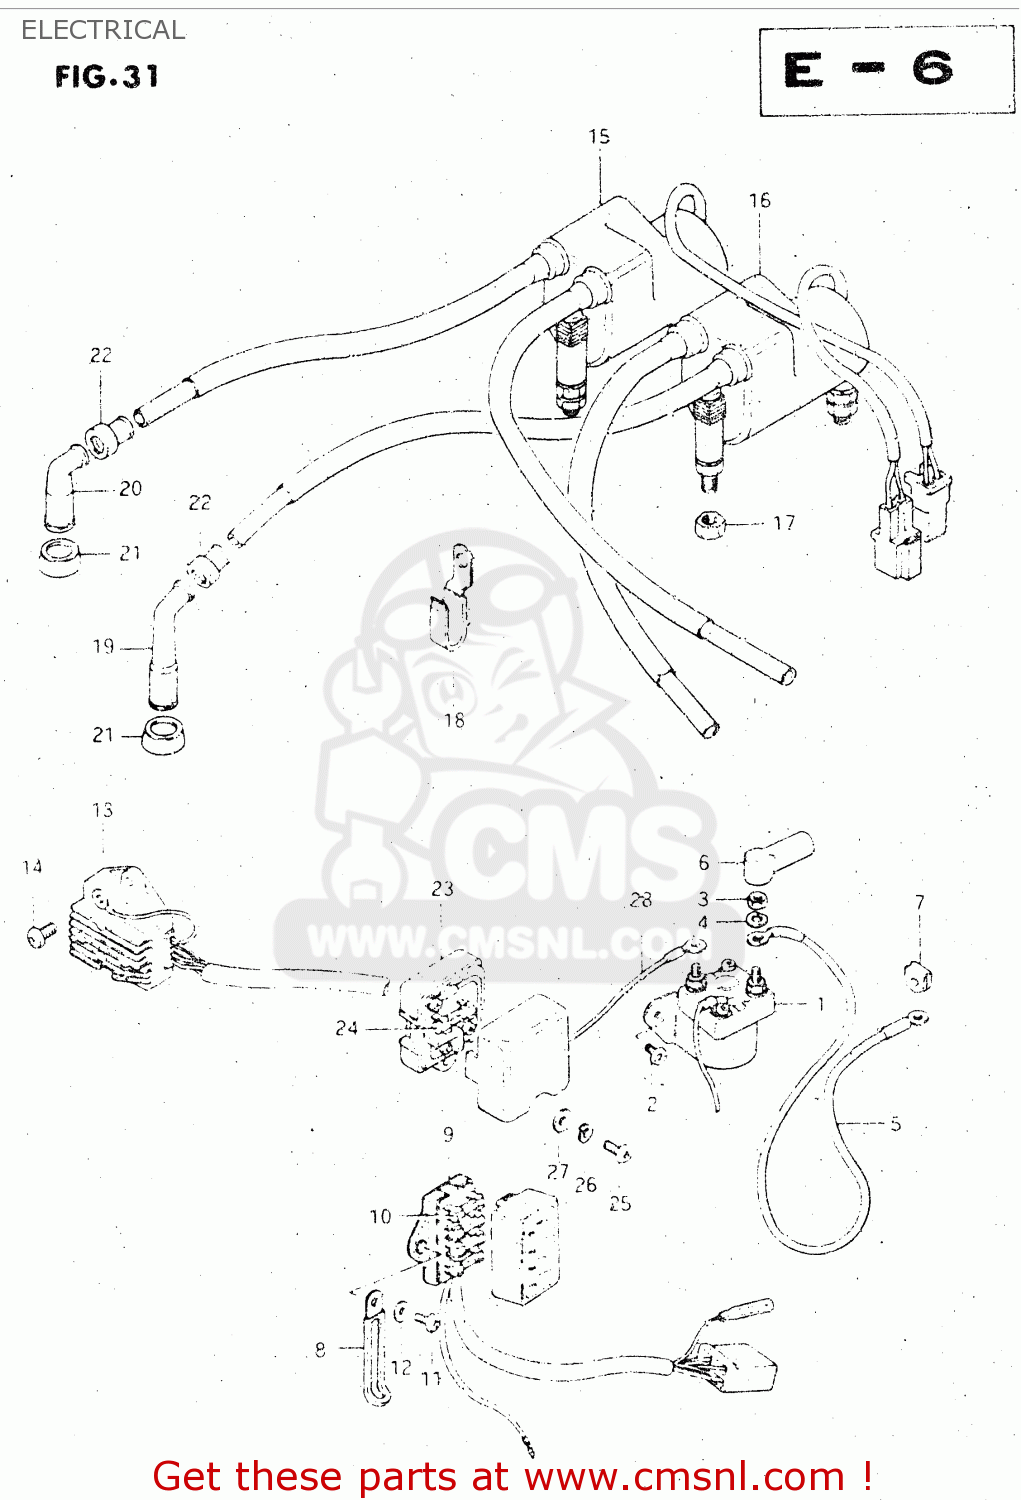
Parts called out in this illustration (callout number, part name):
1	RELAY ASSY,STARTING MOTOR
2	SCREW
3	NUT 6MM
4	LOCK WASHER
5	WIRE,STARTER MOTOR LEAD
6	CAP,STARTER RELAY
7	GROMMET,STARTER CABLE
8	CLAMP
9	BOX ASSEMBLY,FUSE
10	FUSE(15A)
11	SCREW 6X12
12	WASHER
13	RECTIFIER ASSEMBLY
14	SCREW
15	COIL ASSEMBLY,IGNITION
16	COIL ASSEMBLY,IGNITION
17	NUT
18	CLAMP
19	CAP ASSY,SPARK PLUG
20	CAP,SPARK PLUG
21	SEAL,SPARK PLUG
22	SEAL,SPARK PLU
23	TERMINAL ASSEMBLY,POWER SO
24	FUSE(10A)
25	SCREW
26	LOCK WASHER
27	WASHER
28	WIRE
